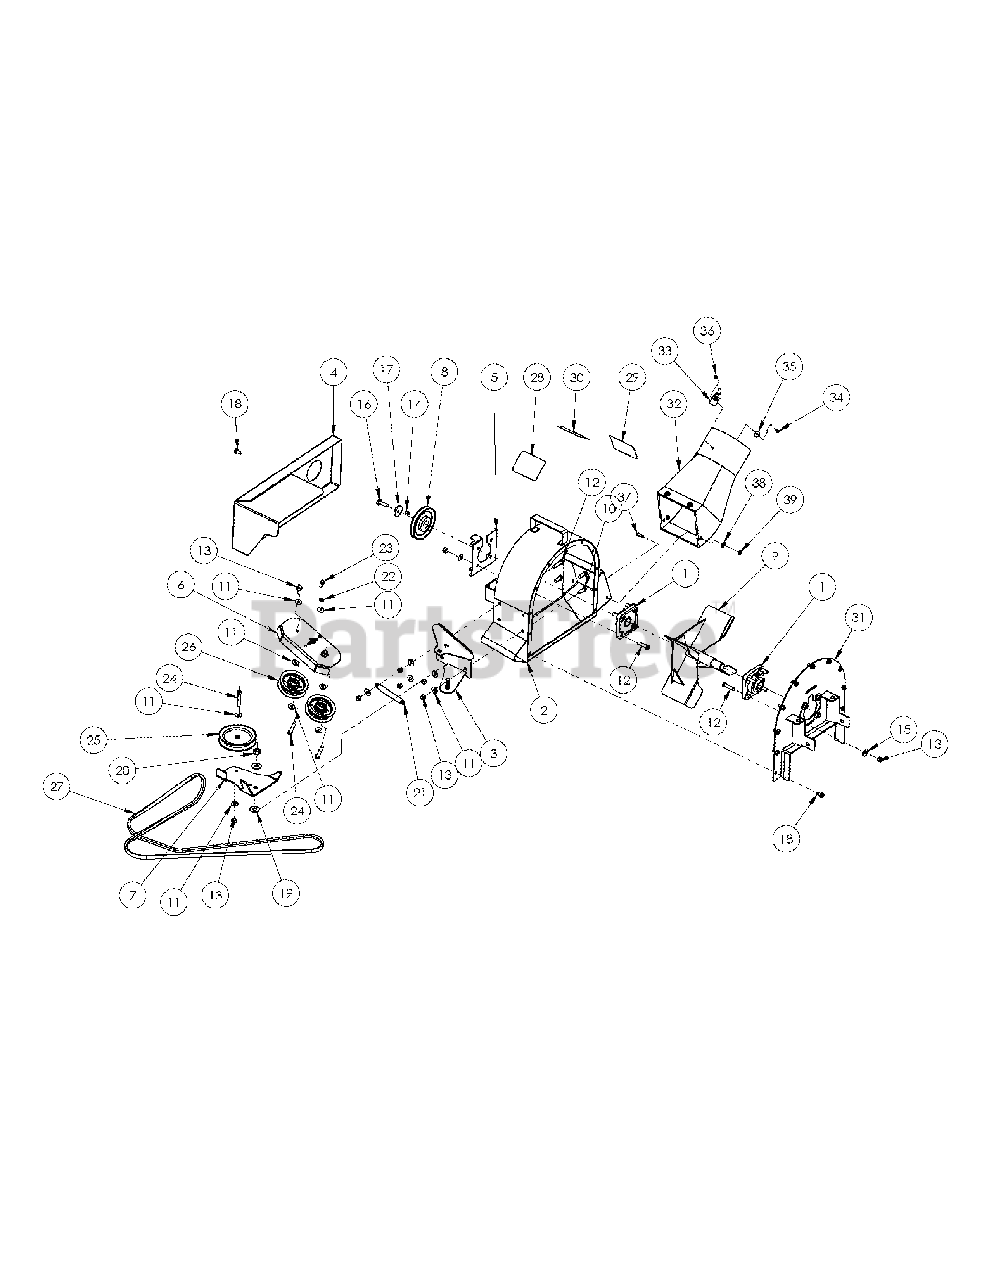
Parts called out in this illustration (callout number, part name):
2	15" VERTICAL BLOWER HOUSING
3	IDLER MOUNT W/A 15" BLOWER
4	EXTERIOR PULLEY COVER 15" BLOWER
5	5" BLOWER PULLEY BELT GUIDE
6	UPPER IDLER MOUNT PLATE
7	IDLER
8	DRIVE PULLEY
9	IMPELLER ASSEMBLY
10	CAP SCREW 3/8-16 X1 LONG
11	5/16" FLAT WASHER
12	CAP SCREW 3/8-16 X 1.50 LONG
13	3/8-16 NYLON INSERT NUT
14	KEY 1/4 SQ X .50 LONG
15	3/8 WASHER SAE
16	CAP SCREW SERATED FLANGE 3/8-16 X 1.25 LONG
17	FLAT WASHER,HEAVY
18	SELF-TAPPING SCREW 5/16 - .625
19	1/2" FLAT WASHER
20	1/2-13 NYLON INSERT NUT
21	BELT DRIVE TENSION SPRING
22	5/16 LOCKWASHER
23	CAP SCREW 5/16-18 X .75 LONG
24	CAP SCREW 3/8-16 X 2.00 LONG
25	INSIDE IDLER
26	IDLER PULLEY, 3" HIGH FLANGE, 3/8" ID
27	BELT, 44" DECK
27	BELT, 48/52" DECKS
28	THROWN OBJECT LABEL
29	TURN OFF MOWER LABEL
30	ROTATING BLADES LABEL
31	ENFORCER BLOWER MOUNT
32	Transition Chute
33	SPRING CLIP
34	#10 x 3/4 SCREW
35	#10 FENDER WASHER
36	#10-24 Nylon Insert Nut
37	CAP SCREW -1/4-20 x .75 LONG
38	1/4" WASHER
39	1/4-20 Nylon Insert Nut
